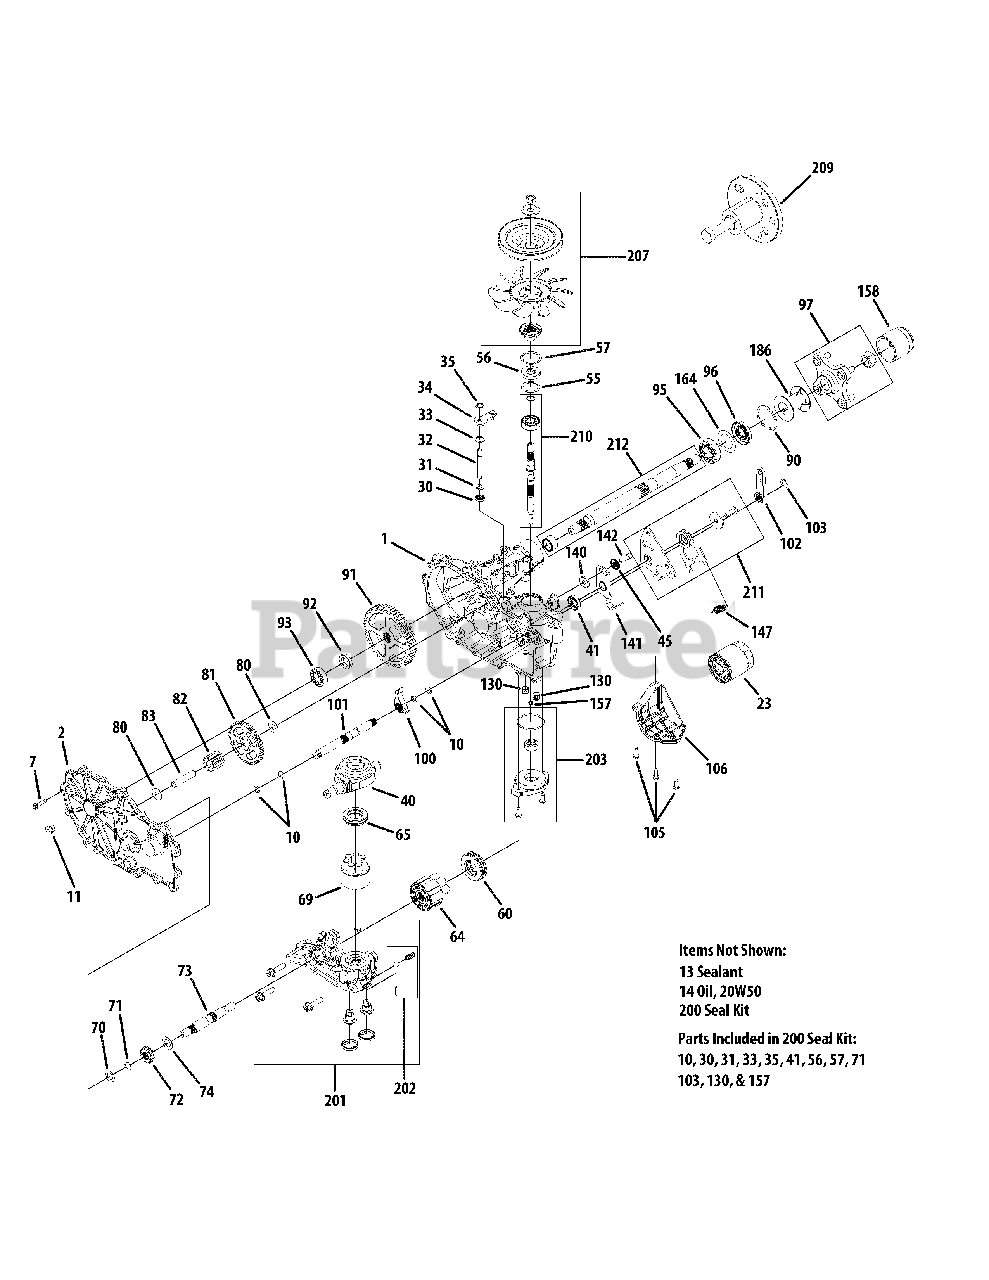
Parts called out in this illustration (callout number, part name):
1	Kit, Main Housing, LH Charge
2	Kit, Side Cover LH
7	Screw, Hex Washer
23	Filter, Spin-On 2.6 x 3.0
30	Seal, Lip, .375 x .75 x .25
31	Ring, Retaining .375 External
32	Rod, Bypass
33	Ring Retaining .750 Internal
34	Arm, Bypass
35	Ring, Ret .375 External
40	Trunnion, Swashplate
41	Seal, Lip 18 x 32 x 7
45	Washer, .34 x .88 x .06
55	Washer, 1.23 x 1.57 x .04
56	Seal, Lip 17 x 40 x 7
57	Ring Retaining Internal
60	Bearing, Thrust 35 x 62 x 18
64	Kit, 16cc Cylinder Block Assembly
65	Thrust Bearing, 30 x 52 x 13
69	Kit, Block, 7 Piston
70	Washer, .63 x 1.00 x .05
71	Ring, Reatining, Motor Shaft
72	Gear, 14T (Steel)
73	Shaft, Motor
74	Washer, .71 x 1.16 x .04
81	Gear, 45T
82	Gear, 11T (Steel)
83	Pin, Jackshaft
90	Ring, Retaining 2.25 Internal
91	Gear, 54T
92	Spacer, .750 x 1.00 x .257
93	Bearing, Ball 3/4 x 40mm x 12mm
95	Bearing, Ball 25.4 x 52 x 15
96	Seal, Lip, 1.0 x 2.06 x .38
97	Kit, Hub 4-Bolt
100	Pawl, Brake
101	Kit, brake Shaft
102	Handle, Actuating
103	Ring, Retaining, External .438
105	Screw, Hex Washer 1/4-20 x .75
106	Guard, Filter, LH
111	Kit, Fitting 1/2 Beaded 9/16 SAE
130	Tube, Charge Triple O-Ring
140	Spacer, .320 x 1.005 x .150
141	Arm, Return Left
142	SHCS, 5/16-24 x 7/8 (W/Patch)
147	Spring, Extension
157	Seal, Gerotor .281 x .420 x .160
158	Cap, Axle
164	Spacer, 1.355 x 2.035 x .021
186	Tube, Axle 2.03
200	Kit. Seal, ZT-2800
201	Kit, Center Section LH Charge
202	Kit, Charge Relief
203	Kit, Charge
207	Kit, Fan Pulley
207	Fan Only
207	Pulley Hub
209	Kit, Hub Puller
210	Kit, Input Shaft
211	Kit, RTN Bidirectional
212	Kit, Shaft Axle
